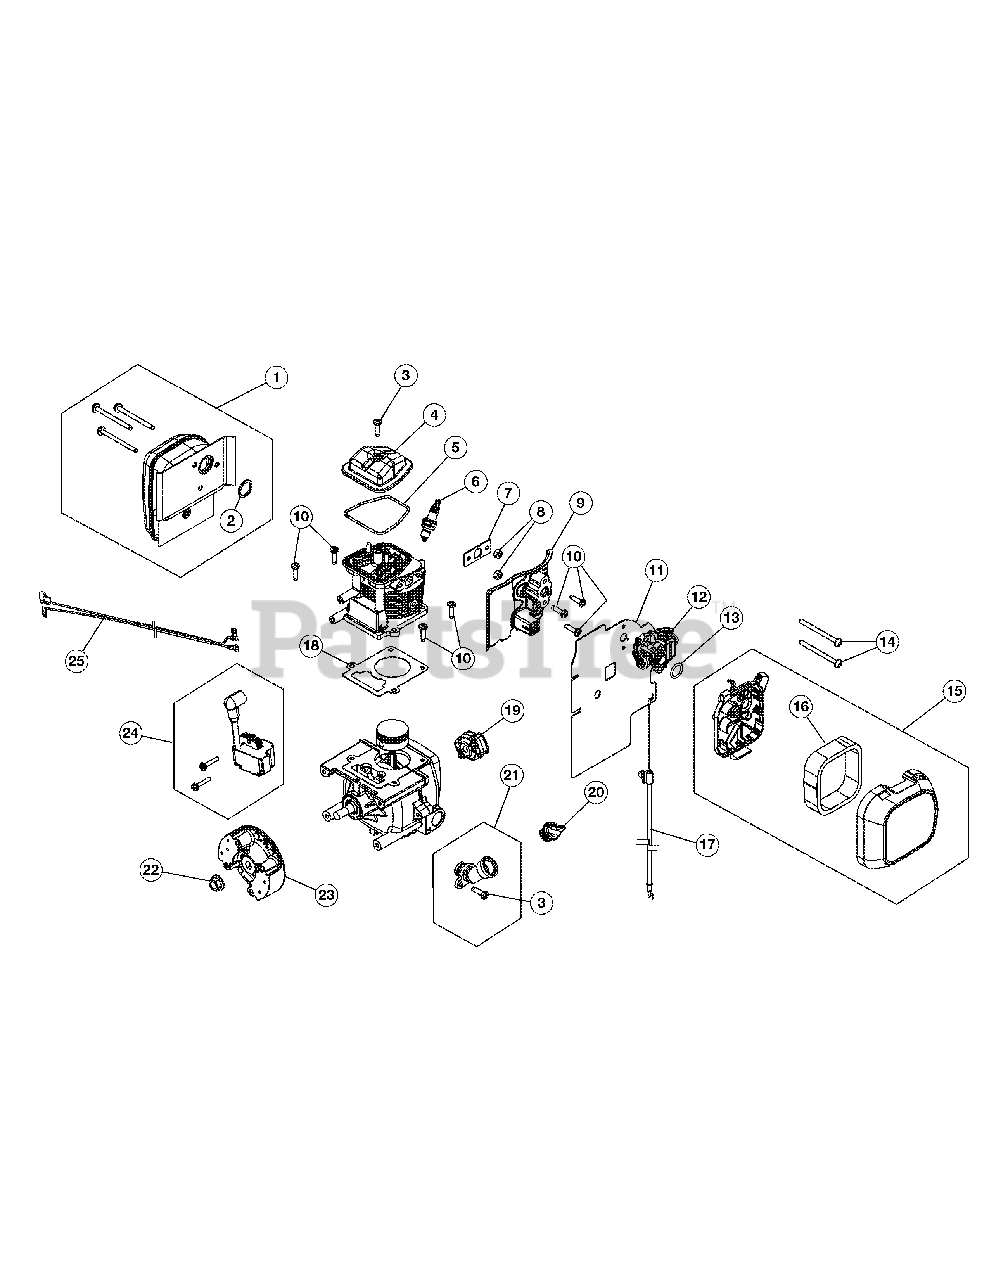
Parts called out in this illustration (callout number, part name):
1	Muffler Assembly (Incl. Ref No. 2)
2	Muffler Gasket
4	Rocker Cover
5	Rocker Cover O-Ring
6	Spark Plug
7	Insulator Gasket
9	Insulator
10	Screw
11	Carburetor Gasket
12	Carburetor
13	Carburetor O-Ring
15	Air Cleaner Assembly (Incl. Ref No. 16)
16	Air Filter
17	Throttle Cable
18	Cylinder Gasket
19	Pawl Assembly
20	Oil Plug
21	Oil Fill Tube (Incl. Ref No. 3)
23	Flywheel Asssembly
24	Module Assembly
25	Lead Wire
